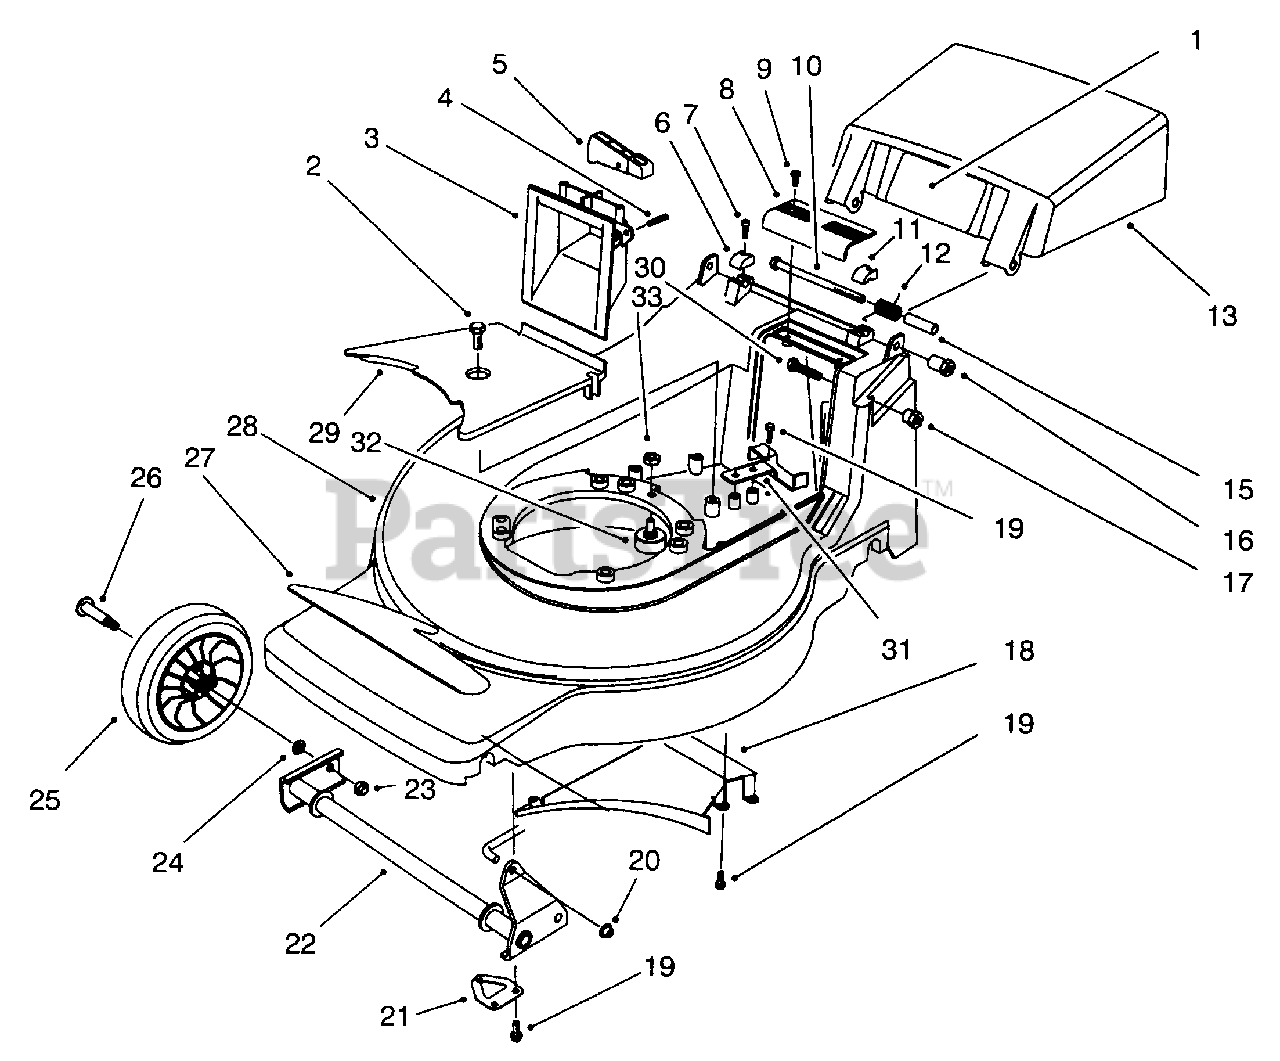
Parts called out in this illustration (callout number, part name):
1	Decal-Danger
2	Screw-Tapping
3	Grip-Lower
4	Pin-Groove
5	Trigger-HOC
6	Cap-R.H. Hinge Bolt
7	Screw-Thread Forming
8	Grip-Upper
9	Screw-Pan Hd. Phillips
10	Screw-Hex Hd. Cap
11	Cap-L.H. Hinge Bolt
12	Spring-Door
13	Door-Discharge (Incl. Ref. #1)
15	Spacer-Door
16	Spacer-Handle
17	Spacer-Handle
18	Ramp-Discharge
19	Screw-Tapping
20	Nut-Push
21	Retainer-Shaft
22	Pivot-Front
23	Nut-Lock
25	Wheel & Tire Assembly
26	Bolt-Wheel
27	Decal-Deck 450VS
28	Housing (Incl. Ref. #1)
29	Cover-Belt
30	Screw-Hex Hd. Cap
31	Guide-Rear Belt
32	Stud-Ball Bearing
33	Nut-Lock
